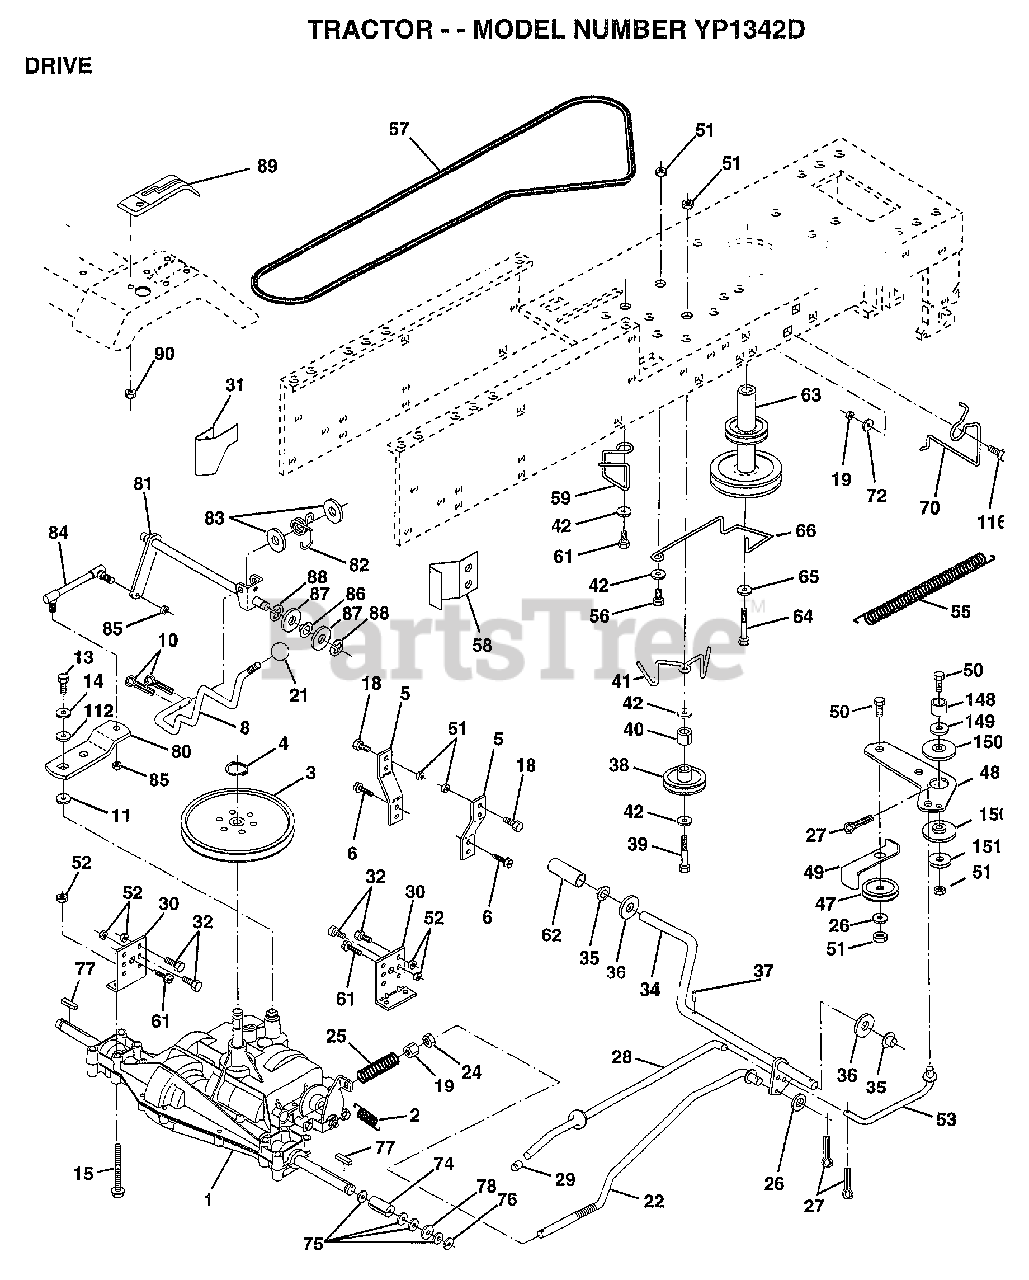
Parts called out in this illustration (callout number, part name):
2	SPRING.BRAKE.RETU
3	PULLEY TRANS
5	STRAP TORQUE
6	SCREW
8	ROD SHIFT FEND LT
10	PIN COTTER 1/8
11	WASH-SHFT PLT LT
13	BOLT.1/4-28.W/PAT
14	LOCKWASHER
15	BOLT.HX.FLG.5/16
18	BOLT
19	NUT
21	KNOB.DUCKHEAD.1/2
22	BRAKE ROD
24	NUT
25	SPRING ROD LT
26	WASHER
27	COTTER PIN
28	ROD.BRAKE.PARK.LT
29	PLUNGER CAP T
30	TRANSAXLE MTG BKT
31	"KEEPER,BELT LH T"
32	BOLT
34	SHAFT ASM-PEDAL F
35	NYLON BEARING
36	WASHER LT
38	PULLEY.IDLER.FLAT
39	BOLT
40	SPACER T
42	WASHER
48	BELLCRANK.CLUTCH
49	RETAIN BELT
53	"LINK, CLUTCH T"
55	"SPRING, RETURN LT"
57	"V-BELT,95.3"
58	"KEEPER,BELT RH T"
59	KEEPER BELT CNTSP
61	SCREW
62	PEDAL COVER T
63	PULLEY.ENGINE
64	BOLT
65	LOCKWASHER
66	KEEPER-BELT
70	KEEPER BELT ENG
72	WASHER
74	SPACER LT
76	E-RING LT
77	SQUARE KEY
78	WASHER
80	SHIFT LEVER
81	SHAFT.CROSS
82	"SPRING,TORSION"
83	WASHER
84	"ROD,TIE "
85	NUT.CNT.LOCK.1/4
86	BUSHING
87	WASHER D
88	KLIP RING
90	NUT
112	WASHER LT
116	BOLT RDHD 3/8-16
149	SPACER RETAINER
150	BUSHING.NYLON
151	WASHER
